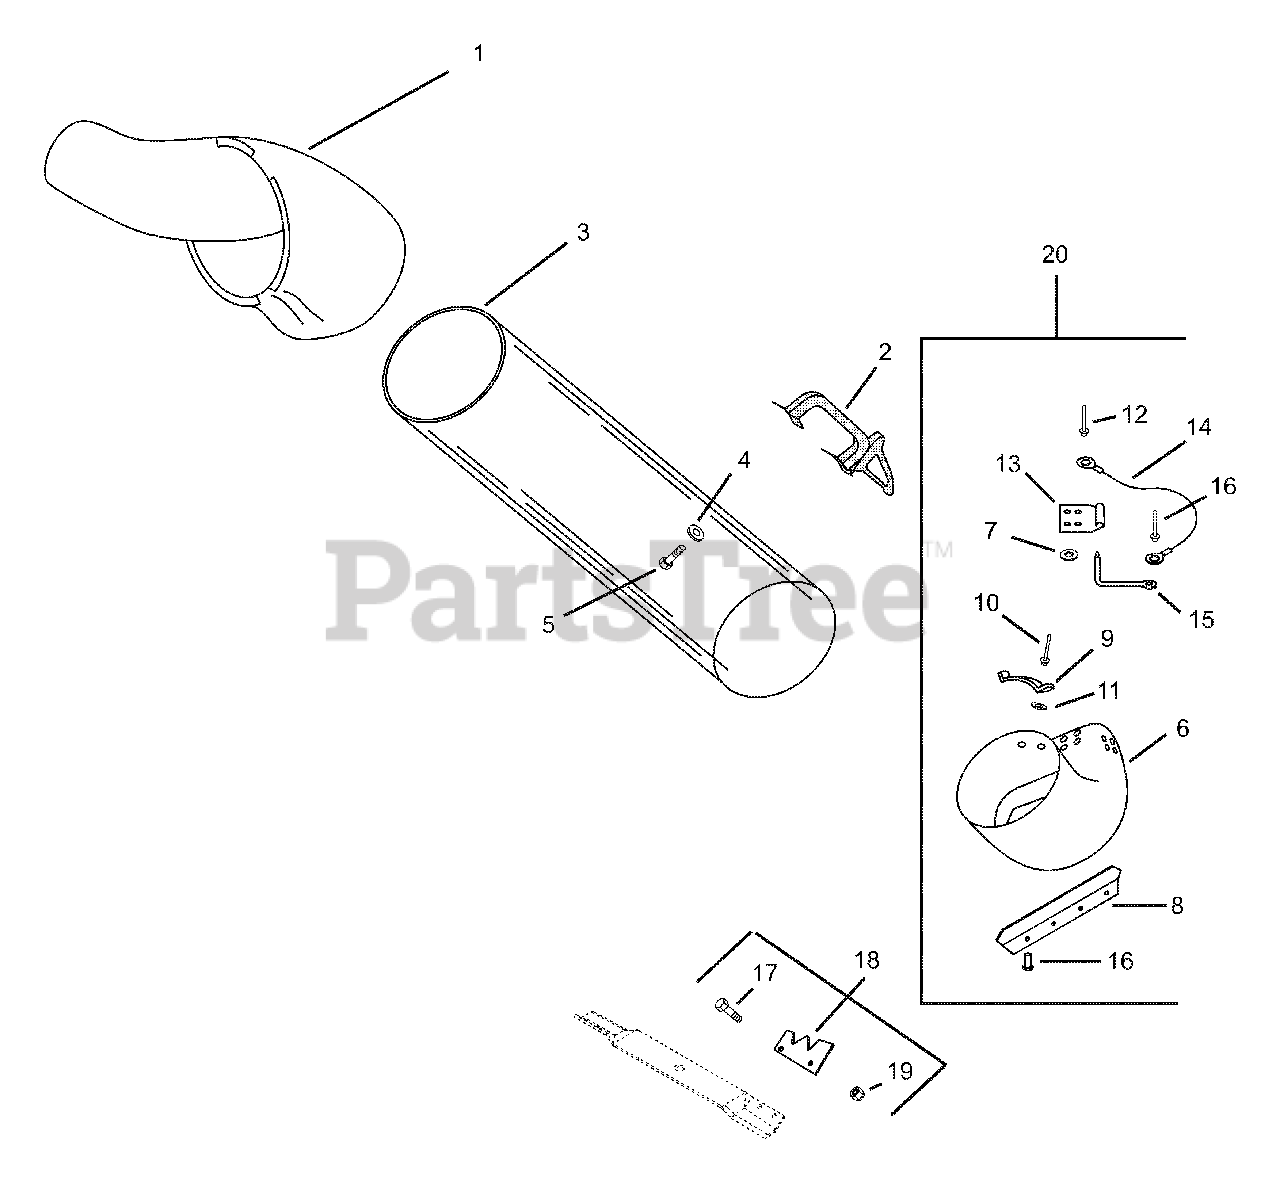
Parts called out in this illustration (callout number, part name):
1	BAGGER BOOT
2	TUBE HANDLE
3	BAGGER TUBE
4	@WSHR-FL-STL.281X.62X.065 YWZC
5	SCR-TAP 10-24X.75 HWH TR YWZC
6	PAN BOOT ASSEMBLY
7	@WSHR-FL-STL.219X.50X.049 YWZC
8	EXTENSION-CHUTE
9	TUBE RETAINER CLIP
10	RVT-POP.187X.527 DOME ST
11	@WSHR-FL-STL.219X.50X.049 YWZC
12	RVT-POP .187X.402 DOME ST
13	BOOT BRACKET
14	LANYARD
15	PULL PIN
16	RVT-TBLR .187X.375 ST-AL PL
17	BLT-HEX .31-24X.75 GR8 YWZC
18	SERVICE VANE PACKAGE
19	NUT-CTRLK .31-24 YWZC
20	MOWER BOOT ASSY- 40"
